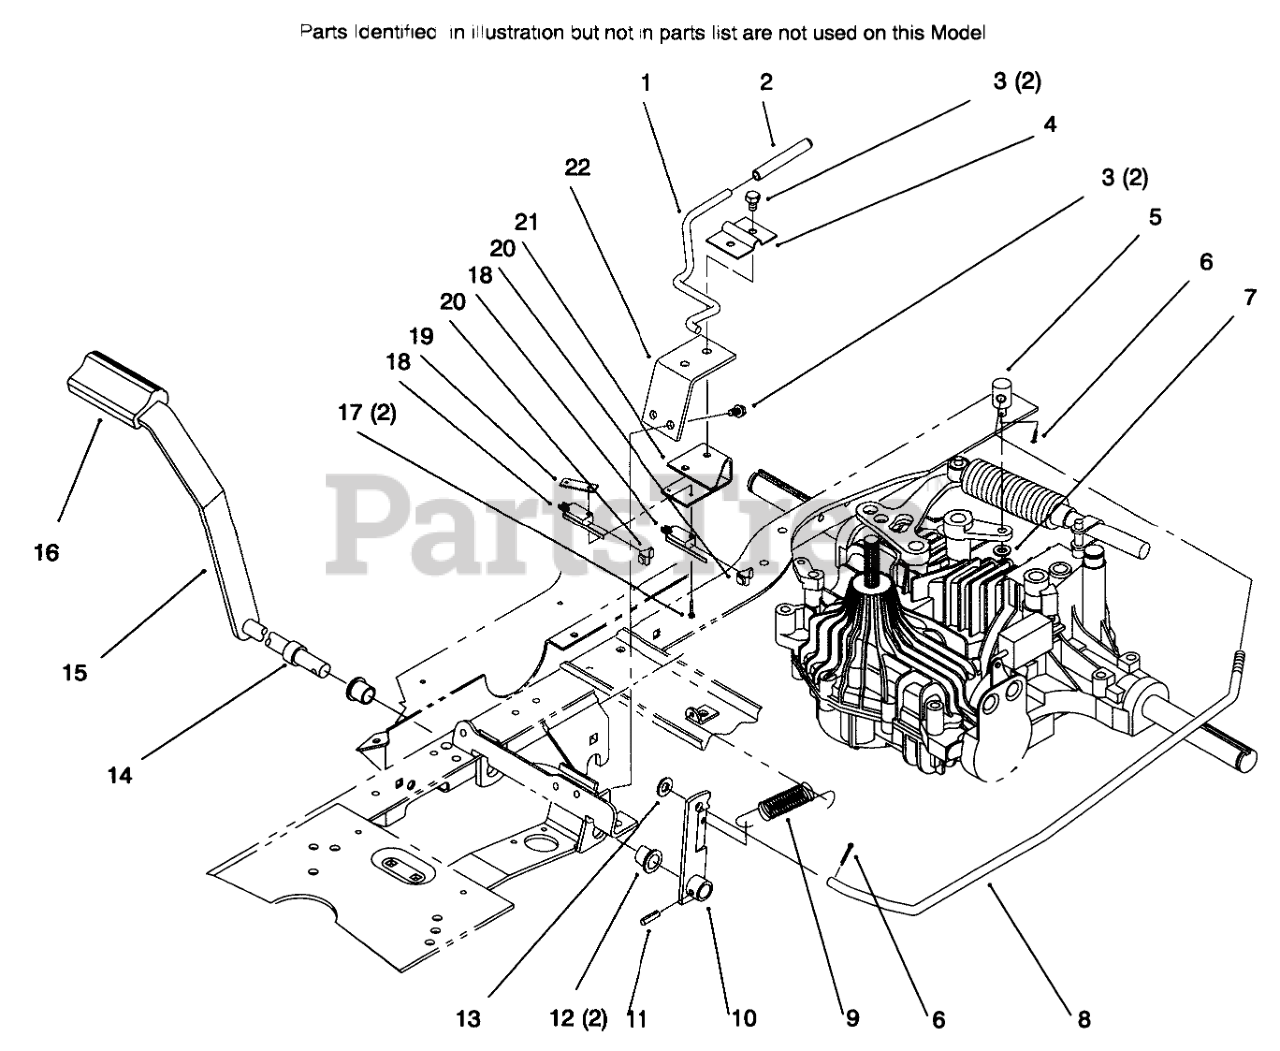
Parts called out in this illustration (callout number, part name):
1	ROD - PARKING BRAKE
2	GRIP - PARKING BRAKE
3	SCREW-HWHTF
4	BRKT-PARKING BRAKE
5	TRUNNION - BRAKE
6	PIN-COTTER
7	WASHER-PLAIN
8	ROD - BRAKE
9	SPRING-EXTENSION
10	WA - BRAKE LEVER
11	PIN-SPRING
12	BUSHING-FLANGE
13	WASHER-FLAT
14	SPACER-BRAKE
15	LEVER - BRAKE WA
16	PAD-PEDAL
16	Tube-Brake
16	Lever-Brake
17	SCREW-HH
18	SWITCH-MICRO
19	NUT-SPEED
20	PLUNGER-SEAL
21	BRKT - BRAKE SWITCH
22	SUPPORT - P. BRAKE
